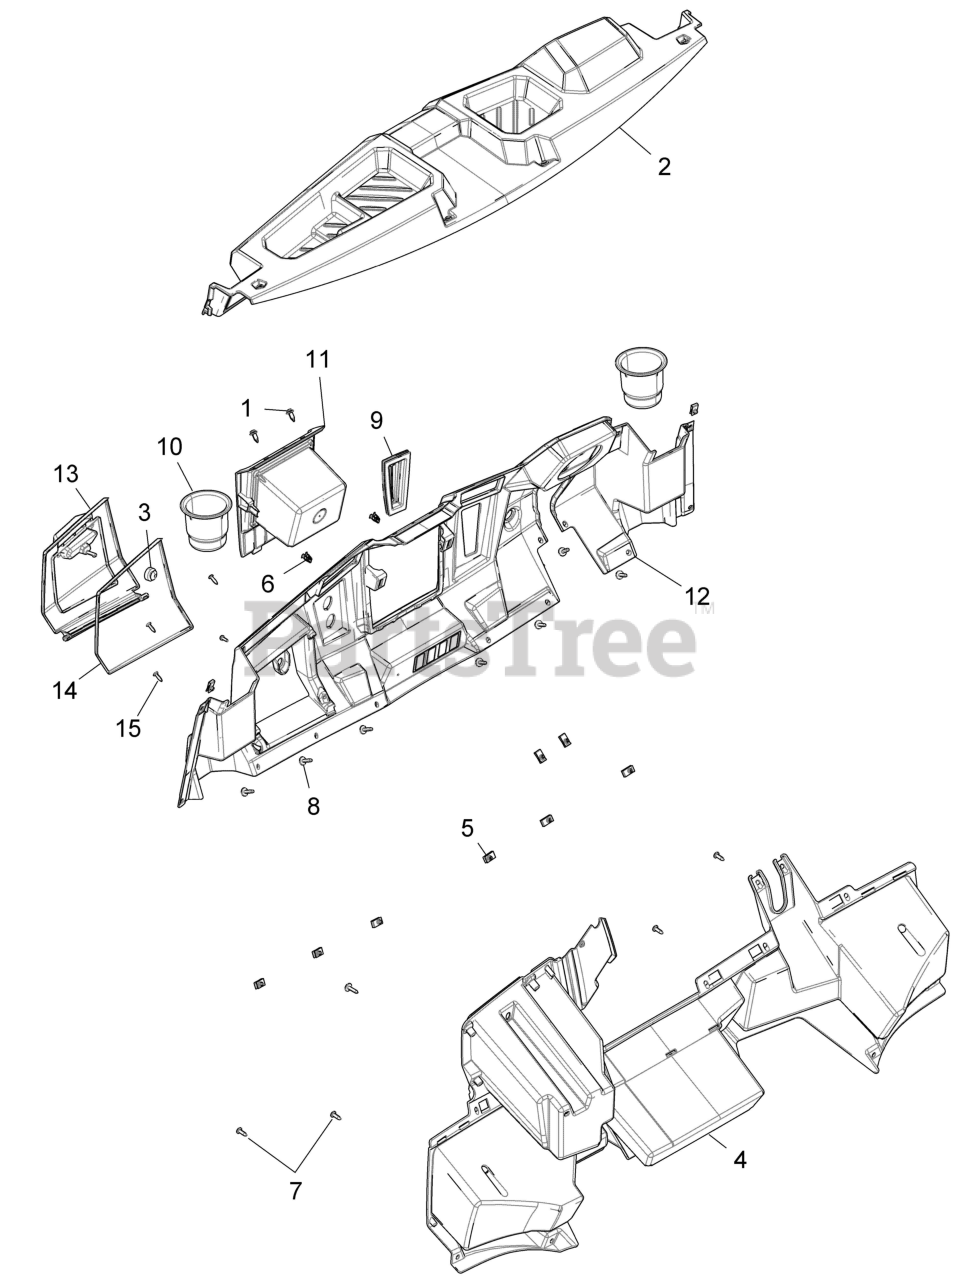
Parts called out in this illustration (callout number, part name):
1	RIVET-TUFLOK,.315-.325X.787 (5
2	DASH, PANEL, UPPER, BLACK
3	GROMMET-RUBBER,MOUNT,25"
4	DASH-STORAGE,RANGER,BLK
5	CLIP-U SPEED NUT
6	CLIP, DASH TRIM METAL
7	SCR-TX TRUSS-#14X3/4,HI/LO ZBK
8	SCR-TXTH-M6X1.0X25 RIE
9	GROMMET-SHIFT LEVER
10	HOLDER-CUP
11	PANEL, DASH, CONTROLS, BLACK
12	DASH, PANEL, LOWER, INDY RED
13	COVER, GLOVEBOX, INDY RED
14	SEAL-GLOVEBOX
